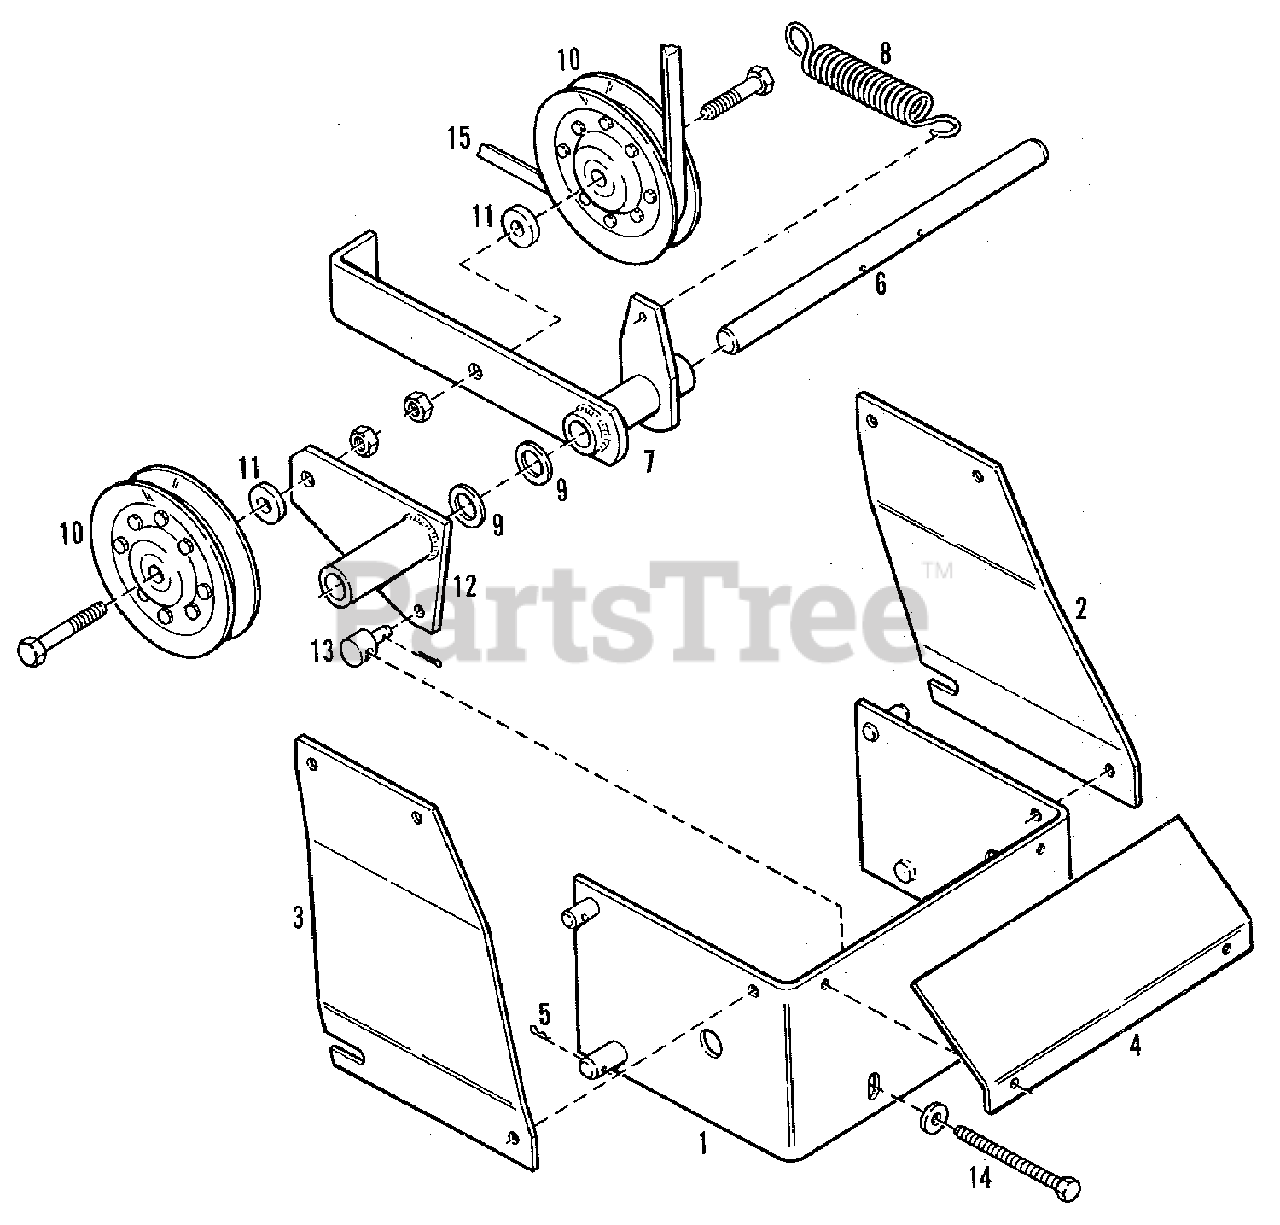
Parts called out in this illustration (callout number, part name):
1	SUPPORT ASSEMBLY, Idler
1	CAPSCREW, 1/2NC x 1-1/2
1	LOCKWASHER, 1/2
2	BRACKET, Hanger, 1/2
2	CAPSCREW, 1/2NC x 1-1/2
2	LOCKWASHER, 1/2
3	BRACKET, Hanger, R.H.
3	CAPSCREW, 1/2NC x 1-1/2
3	LOCKWASHER, 1/2
4	SHIELD, Front, Idler Support
4	SCREW, Hex Head, Thread Cut, 1/4NC x 3/4
4	LOCKWASHER, 1/4
5	PIN, Hair, Cotter, No. 6
6	SHAFT, Idler, Mower
6	PIN, Roll, 1/4 x 1-1/2
7	ARM ASSEMBLY, Idler
8	SPRING, Extension
9	WASHER, Machine, 1" x 10 Ga.
10	IDLER, V-Belt
10	CAPSCREW, 5/8NC x 2-1/2
10	NUT, Lock, 5/8nc
11	SPACER, Front, Idler
12	PLATE, Idler
13	PIN, Adjustment, Idler
13	PIN, Cotter, 5/32 x 1
14	BOLT, Adjusting Pin, Full Thread, 3/8NC x 4-1/2
14	WASHER, Flat, 3/8
15	V-BELT, Mower (Eff. Length 205")
